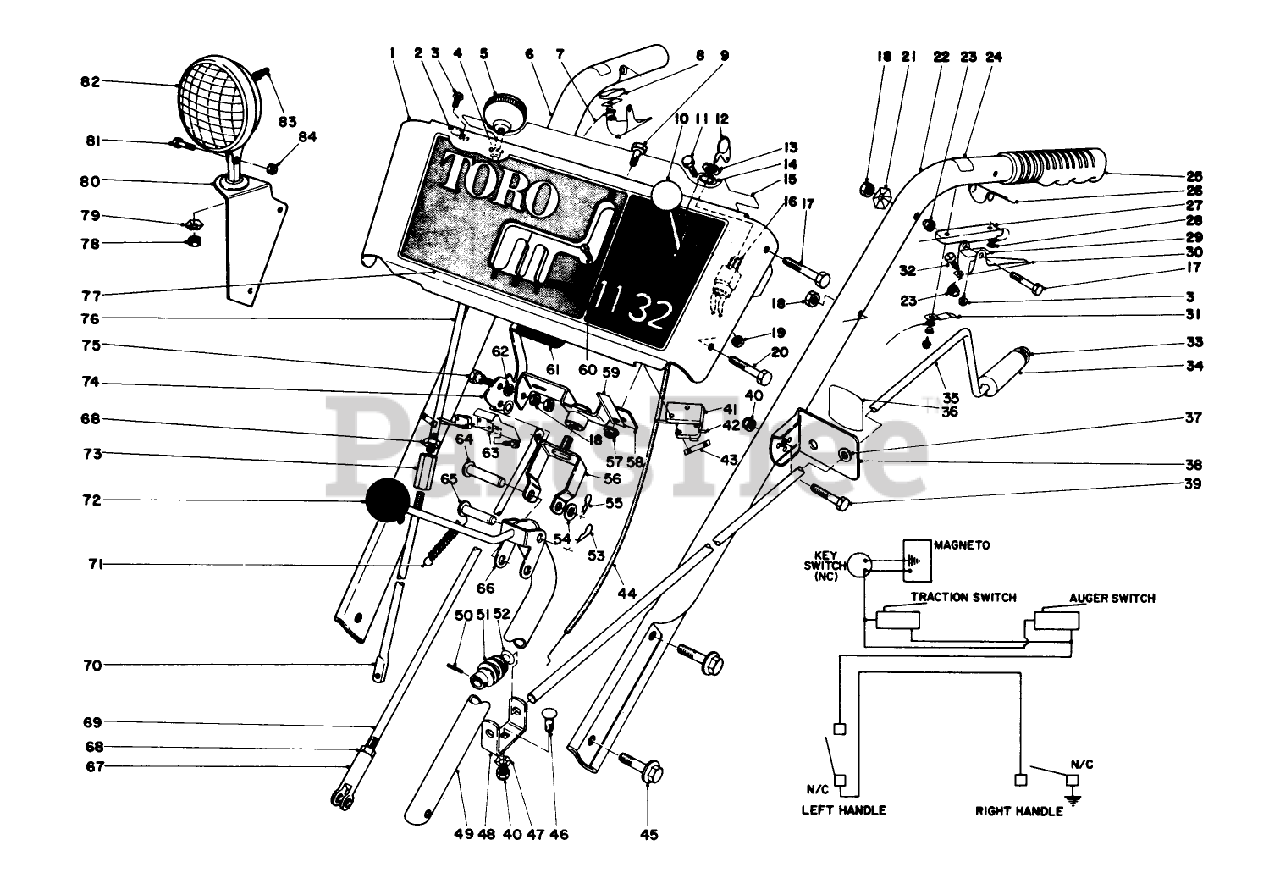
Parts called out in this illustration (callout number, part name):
4	NYLINER #6LI-FF TYPE 7
5	KNOB-LEVER
9	SCREW-HH
13	NUT-HH
14	SCREW-SET
16	SWITCH-ON / OFF
17	SCREW-HH
18	NUT-LOCK, CONE
20	SCREW-HH
22	LEFT HANDLE
23	NUT-CAP
27	DUAL BRKT INSULATOR
28	BUSHING-INSULATOR
29	INTERLOCK CONTACT
31	CONTACT BRACKET
32	NYLON SCREW 1/4 20
33	NUT-PUSH
34	GRIP-CONTROL, CHUTE
39	SCREW-HH
40	NUT-LOCK, NI
43	Speed Nut
45	SCREW-HHF
46	BOLT-CARR
47	WASHER-LOCK
50	PIN-SPRING
51	GEAR-WORM, CHUTE
52	WASHER-SPRING
54	WASHER-FLAT
55	PIN-HAIR
57	NUT-LOCK, HHF
60	SCREW-SPH
62	WASHER-PLAIN
63	SWITCH BRKT
64	PIN-CLEVIS
65	PIN-CLEVIS
66	SHIFT ROD WA
67	CLEVIS
68	NUT-HJ
70	LOWER WHL CLUTCH ROD
73	WHL ROD COUPLING
75	SCREW-SHOULDER
78	NUT-HEX
79	LOCKWASHER-PYRAMID
81	SCREW-HH
83	BOOT-SWITCH
84	NUT-HEX, SIDE DEFORM
